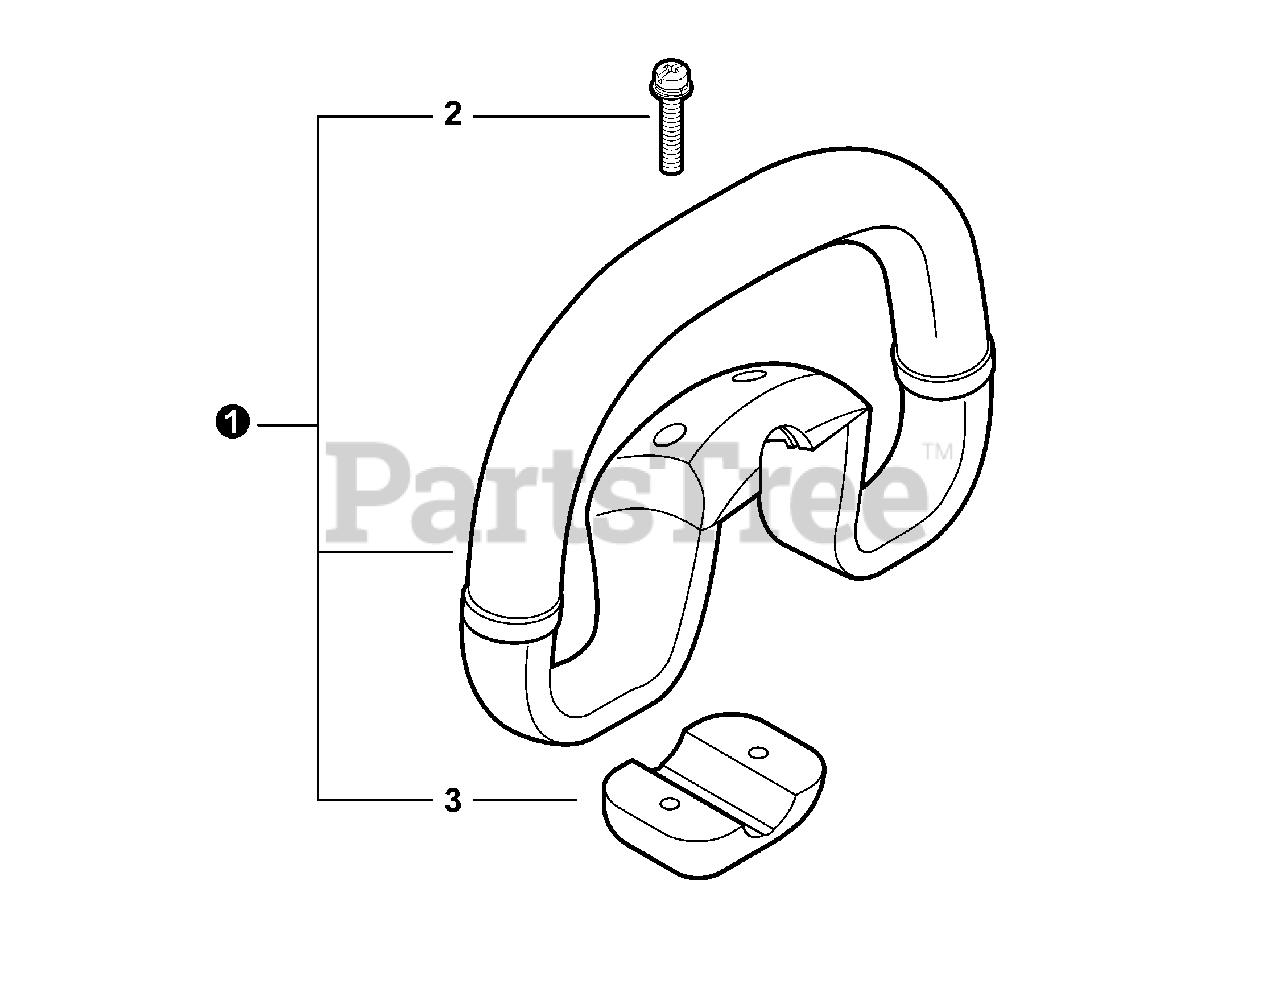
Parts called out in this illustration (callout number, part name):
1	HANDLE ASSY - SUPPORT
2	SCREW 5×40
3	BRACKET, HANDLE
